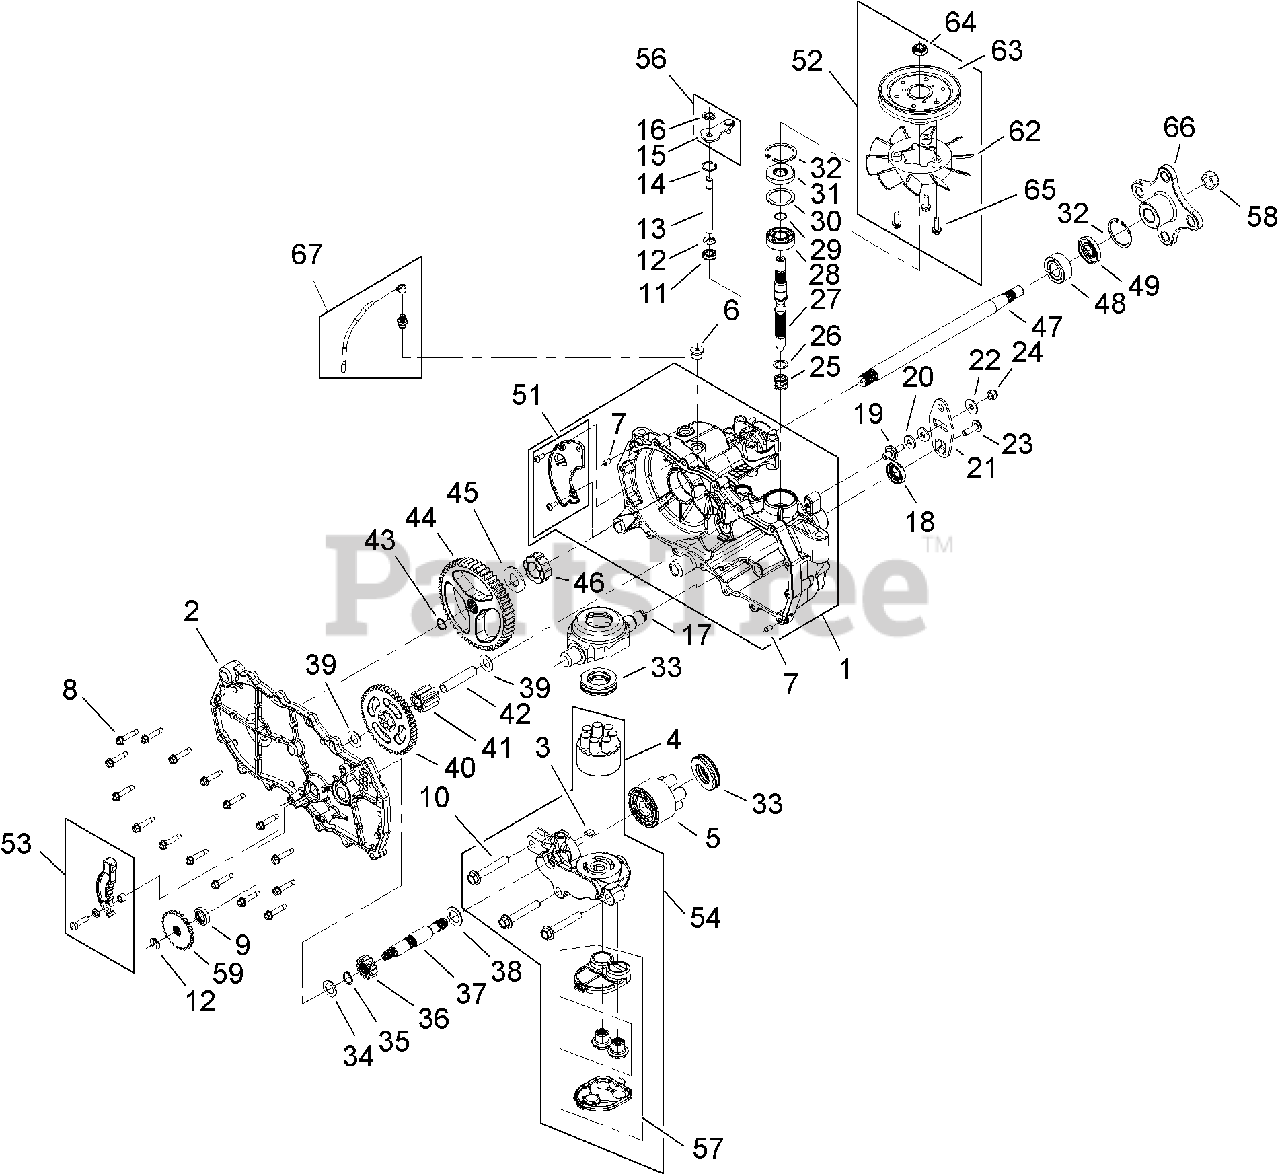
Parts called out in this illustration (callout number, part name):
1	LH MAIN HOUSING ASM
2	LH SIDE ASM
3	PLATE-BYPASS
4	PUMP BLOCK ASM
5	CYLINDER BLOCK ASM
6	PLUG
8	SCREW-HHF
9	BRAKE SEAL KIT
11	SEAL-LIP
12	RING-RETAINING, EXT
13	ROD-BYPASS
14	RING-RETAINING, INT
15	ARM-BYPASS
16	RING-RETAINING, EXT
17	SWASHPLATE-TRUNNION
20	PUCK-FRICTION
21	ARM-CONTROL
22	WASHER-PIVOT
25	SPRING-BLOCK
26	WASHER-BLOCK, THRUST
27	SHAFT-INPUT
28	BEARING-BALL
29	RING-RETAINING
32	RING-RETAINING
33	BEARING-THRUST
34	WASHER-FLAT
35	RING-RETAINING
36	GEAR-PINNION, 13T
37	SHAFT-MOTOR
38	WASHER-SHAFT, MOTOR
41	GEAR-JACKSHAFT, 10T
42	PIN-JACKSHAFT
43	RING-SPIRAL, RETAINING
44	GEAR-52T BULL
46	BEARING-SLEEVE
47	SHAFT-AXLE
48	BUSHING-AXLE
51	LH EXPANSION PLATE KIT
52	FAN PULLEY KIT
53	BRAKE ARM KIT
54	LH CENTER SECTION FILTER KIT
56	BYPASS ARM KIT
57	FILTER KIT
59	DISC-BRAKE, COG
62	FAN
63	PULLEY
67	BREATHER KIT
